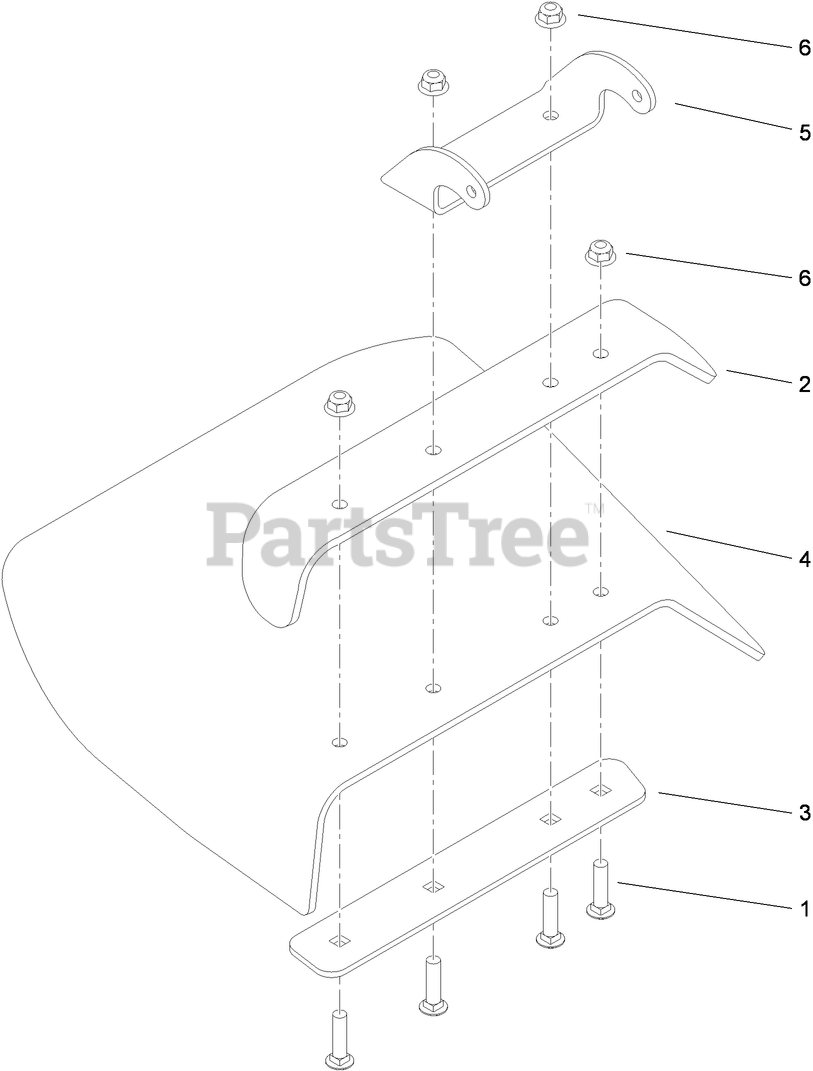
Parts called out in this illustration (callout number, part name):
1	SCREW-CARR
2	DEFLECTOR
3	STRAP-DISCHARGE
4	DEFLECTOR-RUBBER
5	BRACKET-MOUNTING, DEFLECTOR
6	NUT-HF, NI
